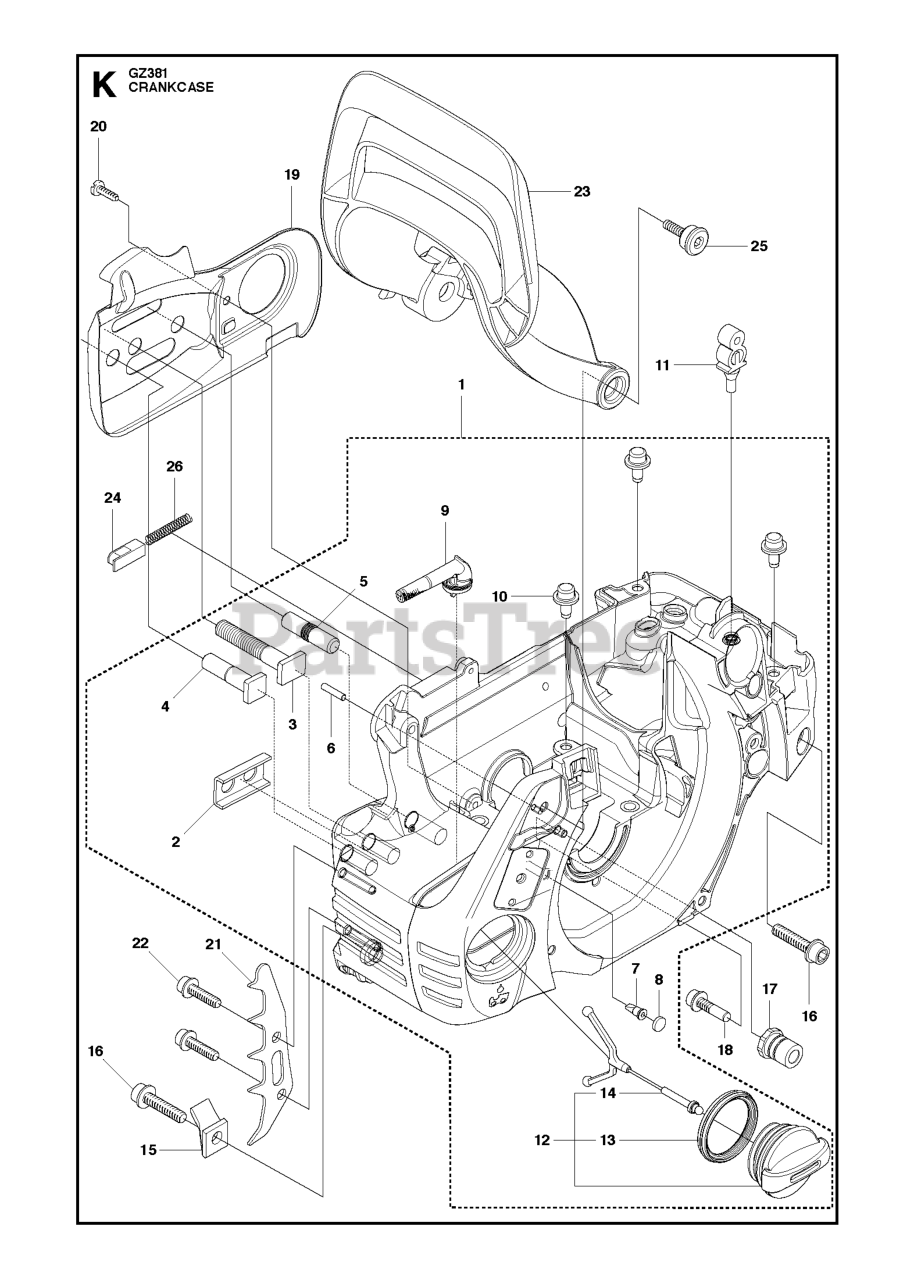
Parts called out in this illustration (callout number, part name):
1	CRANKCASE ASSY
2	STIFFENING PLATE
3	BAR BOLT
4	BAR BOLT (X2)
5	BAR BOLT
7	VALVE-CHECK (DUCKBILL)
8	FILTER
9	OIL SCREEN
10	GUIDE PEN
11	CARBURETOR MOUNTING
12	TANK CAP ASSY
14	TANK LOCK
15	CHAIN CATCHER PIN
17	LATERAL SUPPORT
18	SCREW IHSCFT
19	CHAIN GUIDE PLATE
20	SCREW CCRPANT
21	SPIKE INNER
23	HAND GUARD
26	POSITION SPRING
